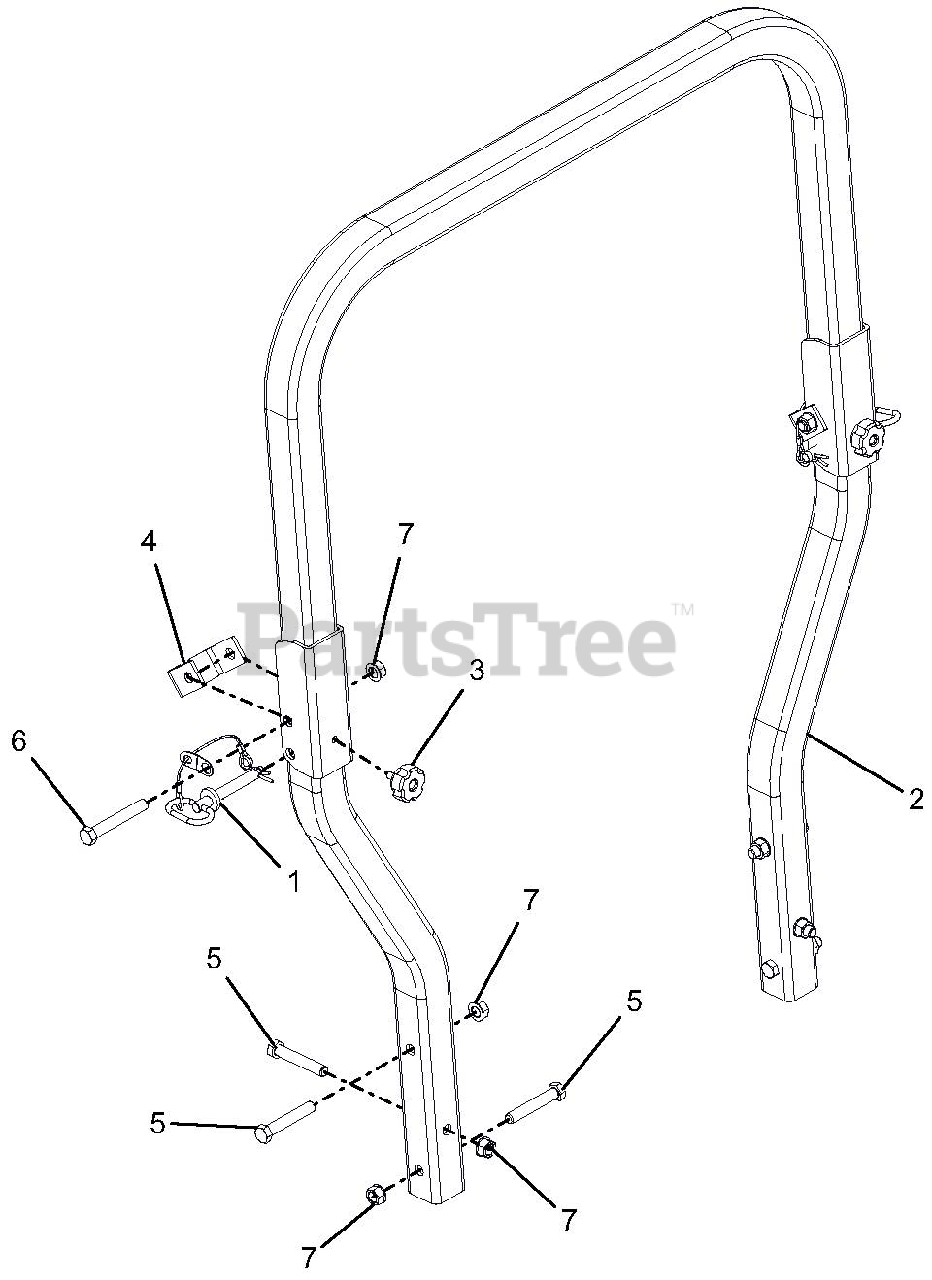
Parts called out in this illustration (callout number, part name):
1	ASSY, ROPS PIN/LANYARD
2	ROPS INCLUDES HOOP RH AND LH SUPPORT
3	KNOB, ROUND 5/16-18 X .750
4	BRKT, ROPS STOP
5	@BLT-HEX .50-13X3.00 GR5 YWZC
6	@BLT-HEX .50-13X3.50 GR5 YWZC
7	@NUT-LK-TOP-FLG .50-13 YWZC
